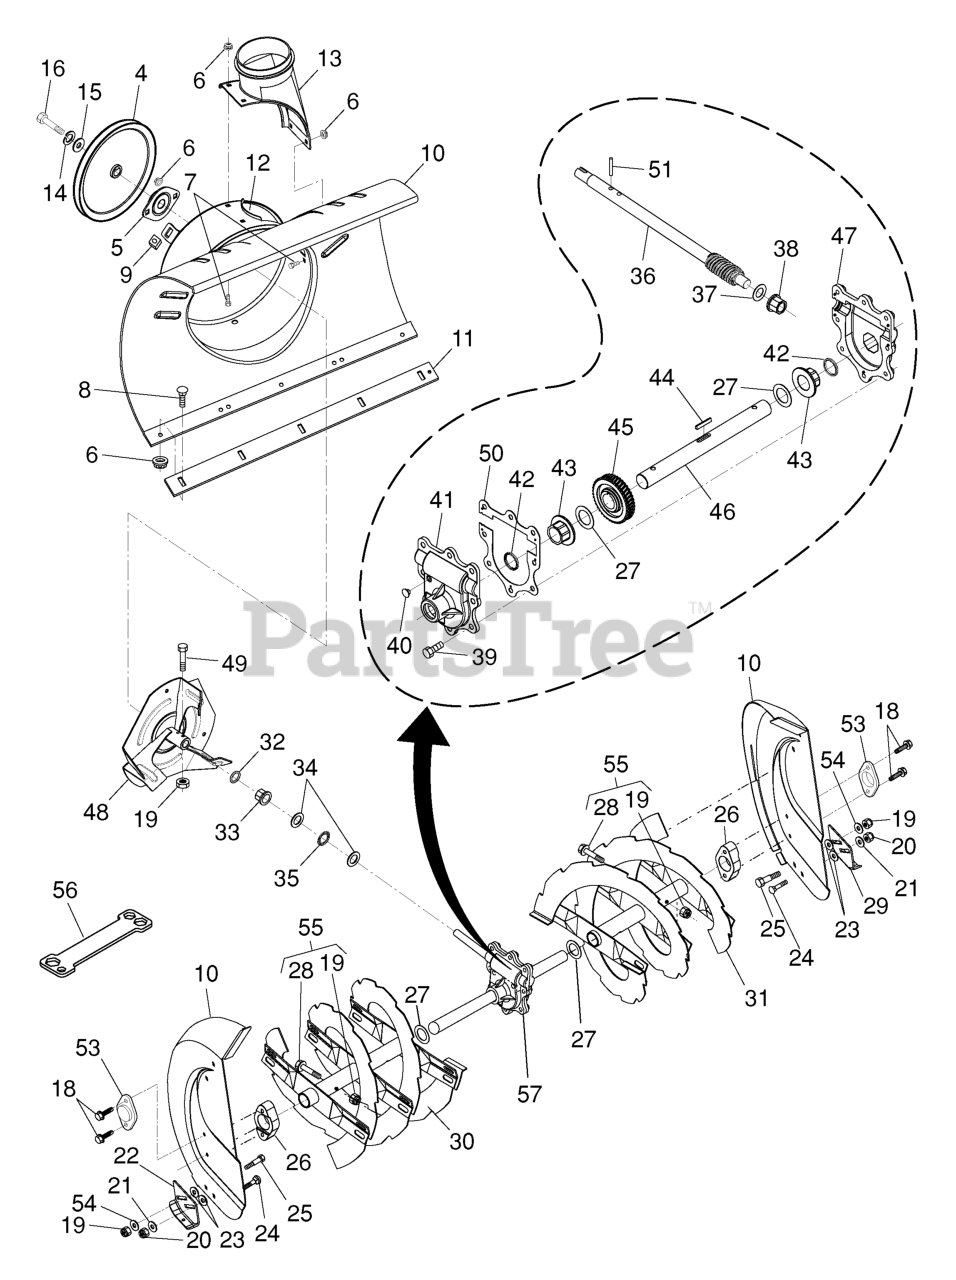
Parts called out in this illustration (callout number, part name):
4	PULLEY, IMPELLER
5	BEARING FLANGE
6	NUT.FLANGE.5/16
7	BOLT.CARRIAGE.5/16-18X
8	BOLT
9	NUT, CAGE 3/8-16
10	HOUSING, AUGER
11	BAR, SCRAPER 30"
12	BRACKET, CORNER DISCHARGE
13	BASE DISCHARGE CHUTE
14	WASHER, FLAT
15	WASHER.LOCK.HVY.HLCL.SPR.5/16
16	Screw, Hex Head 5/16-18 x 3/4
18	SCREW, HEX HD 5/16X1
19	LOCKNUT.NYLOC.1/4-20
20	NUT.71038.31-18.HEX.NYLOCK
21	WASHER.20X8.5
22	SKID PLATE RH
23	WASHER, NYLON FRICTION
24	BOLT
25	SHOULDER BOLT
26	BEARING RETAINER, PLASTIC
27	WASHER TRUST 1"
28	BOLT.SHOULDER.SHEAR.1/4-20.
29	SKID PLATE LH
30	AUGR.ASM.30".RH.PNT
31	AUGR.ASM.30".LH.PNT
33	BUSHING FLANGE 3/4
34	WASHER, THRUST 3/4
35	BEARING TRUST 3/4 NTA-1220
36	SHAFT, IMPELLER
37	WASHER, THRUST 5/8
38	BUSHING.FLANGE.(.625X.75)
39	SELF-TAPPING SCREW 5/16-18X3/4
40	PLUG.AUGER.GEAR.BOX.SNOW
41	HOUSING.GEARBOX.RH.SNOW
43	BUSHING FLANGE 1"
44	KEY, SQUARE 1/4 X .875
45	WORM GEAR
46	SHAFT, AUGER
47	LH GEARBOX HOUSING
48	IMPELLER ASSY
49	SCREW.HEX.HD1/4-20X
50	GASKET.AUGER.GEARBOX
51	PIN, ROLL 3/16 X 1-1/8
53	BEARING.BALL.AUGER.SHAFT
54	WASHER
55	KIT, BOLT, SHEAR
56	RP WRENCH, SNOWTHROWER
57	AUGER GEARBOX (COMPLETE)
